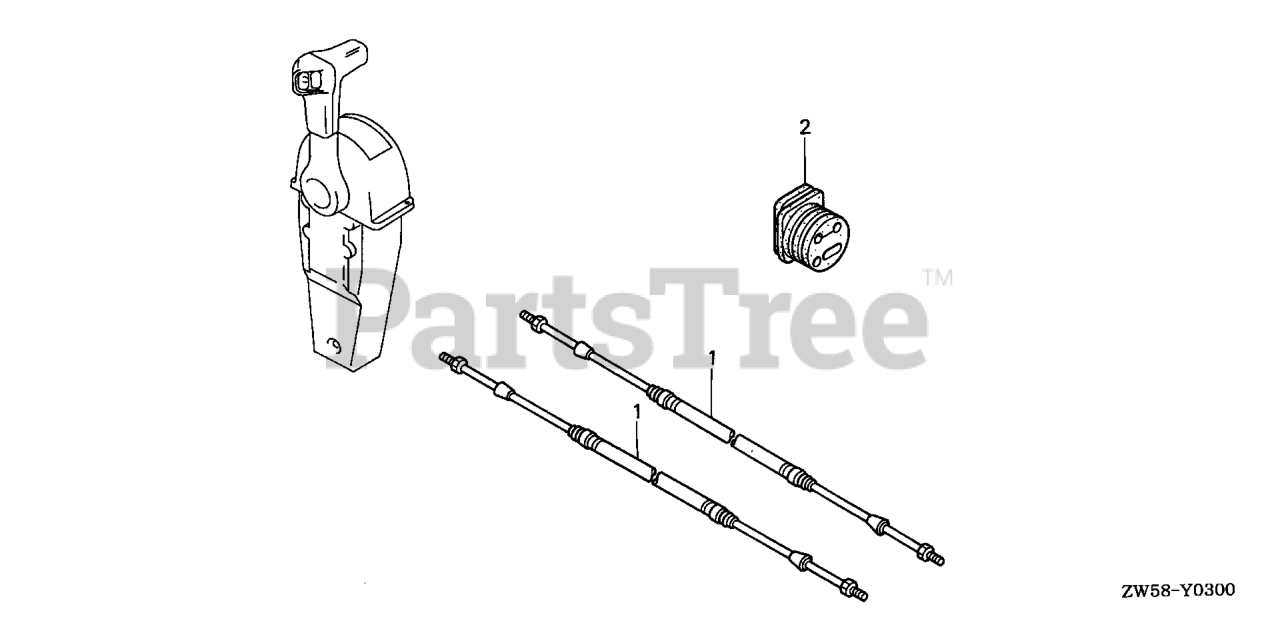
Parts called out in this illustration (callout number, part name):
1	CABLE, REMOTE CONTROL (10'') (LOW FRICTION)
1	CABLE ASSY., PUSH-PULL (33C-5FT)
1	CABLE, REMOTE CONTROL (11'') (LOW FRICTION)
1	CABLE ASSY., PUSH-PULL (33C-6FT)
1	CABLE, REMOTE CONTROL (12'') (LOW FRICTION)
1	CABLE ASSY., PUSH-PULL (33C-7FT)
1	CABLE, REMOTE CONTROL (13'') (LOW FRICTION)
1	CABLE ASSY., PUSH-PULL (33C-8FT)
1	CABLE, REMOTE CONTROL (14'') (LOW FRICTION)
1	CABLE ASSY., PUSH-PULL (33C-9F T)
1	CABLE, REMOTE CONTROL (15'') (LOW FRICTION)
1	CABLE ASSY., PUSH-PULL (33C-10FT)
1	CABLE, REMOTE CONTROL (16'') (LOW FRICTION) (NOT AVAILABLE)
1	CABLE ASSY., PUSH-PULL (33C-11FT)
1	CABLE, REMOTE CONTROL (17'') (LOW FRICTION)
1	CABLE ASSY., PUSH-PULL (33C-12 FT)
1	CABLE, REMOTE CONTROL (18') (LOW FRICTION) (NOT AVAILABLE)
1	CABLE ASSY., PUSH-PULL (33C-13 FT)
1	CABLE, REMOTE CONTROL (1 9'') (LOW FRICTION)
1	CABLE ASSY., PUSH-PULL (33C-14FT)
1	CABLE, REMOTE CONTROL (20'') (LOW FRICTION) (NOT AVAILABLE)
1	CABLE ASSY., PUSH-PULL (33C-15 FT)
1	CABLE, REMOTE CONTROL (21') (LOW FRICTION)
1	CABLE ASSY., PUSH-PULL (33C-16FT)
1	CABLE, REMOTE CONTROL (22') (LOW FRICTION) (NOT AVAILABLE)
1	CABLE ASSY., PUSH-PULL (33C-17 FT)
1	CABLE, REMOTE CONTROL (2 3'') (LOW FRICTION)
1	CABLE ASSY., PUSH-PULL (33C-18 FT)
1	CABLE, REMOTE CONTROL (24') (LOW FRICTION) (NOT AVAILABLE)
1	CABLE ASSY., PUSH-PULL (33C-19FT)
1	CABLE, REMOTE CONTROL (25') (LOW FRICTION)
1	CABLE ASSY., PUSH-PULL (33C-20FT)
1	CABLE, REMOTE CONTROL (26') (LOW FRICTION)
1	CABLE ASSY., PUSH-PULL (33C-21FT)
1	CABLE, REMOTE CONTROL (27') (LOW FRICTION)
1	CABLE ASSY., PUSH-PULL (33C-22FT)
1	CABLE, REMOTE CONTROL (28') (LOW FRICTION) (NOT AVAILABLE)
1	CABLE ASSY., PUSH-PULL (33C-23FT)
1	CABLE, REMOTE CONTROL (2 9') (LOW FRICTION)
1	CABLE ASSY., PUSH-PULL (33C-24FT)
1	CABLE, REMOTE CONTROL (30') (LOW FRICTION) (NOT AVAILABLE)
1	CABLE ASSY., PUSH-PULL (33C-25FT)
1	CABLE, REMOTE CONTROL (31') (LOW FRICTION)
1	CABLE ASSY., PUSH-PULL (33C-26FT)
1	CABLE, REMOTE CONTROL (32') (LOW FRICTION) (NOT AVAILABLE)
1	CABLE ASSY., PUSH-PULL (33C-27FT)
1	CABLE, REMOTE CONTROL (33') (LOW FRICTION)
1	CABLE ASSY., PUSH-PULL (33C-28FT)
1	CABLE, REMOTE CONTROL (34') (LOW FRICTION)
1	CABLE ASSY., PUSH-PULL (33C-29FT)
1	CABLE, REMOTE CONTROL (35') (LOW FRICTION)
1	CABLE ASSY., PUSH-PULL (33C-30FT)
1	CABLE ASSY., PUSH-PULL (33C-31FT)
1	CABLE ASSY., PUSH-PULL (33C-32FT)
2	GROMMET, CASE (LOWER) (B)
